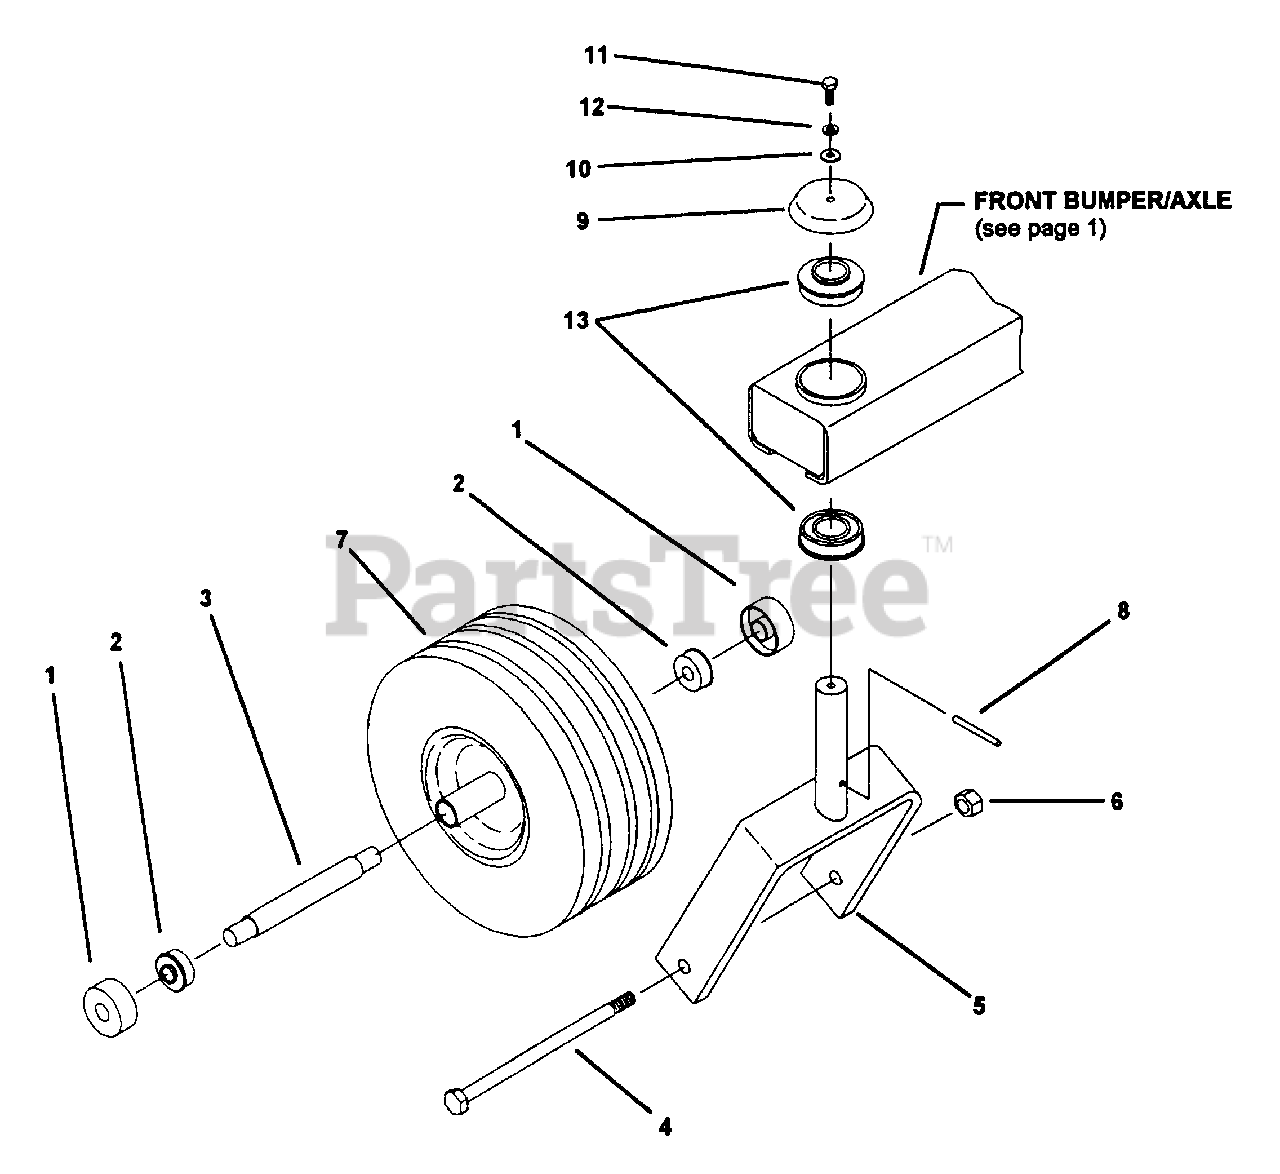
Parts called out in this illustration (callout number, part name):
1	SHIELD, BEARING
2	BEARING, 5/8 I.D. X 1-3/8 O.D.
3	SPACER, BEARING
4	BOLT, 1/2-13 X 8" GR.5
5	CASTER WELDMENT
6	NUT, 1/2-13, STOVER
7	TIRE, 13X5-8, ON WHEEL,
8	PIN, SPIRAL, 3/16 X 2 HEAVY DUTY
9	CAP, BEARING
10	WASHER, FLAT STD. 1/4"
11	BOLT, 1/4-20 X 5/8" GR.5
12	LOCKWASHER, 1/4" HEAVY SPRING
13	BEARING, SPD SF-16-32 W/O COLLAR
